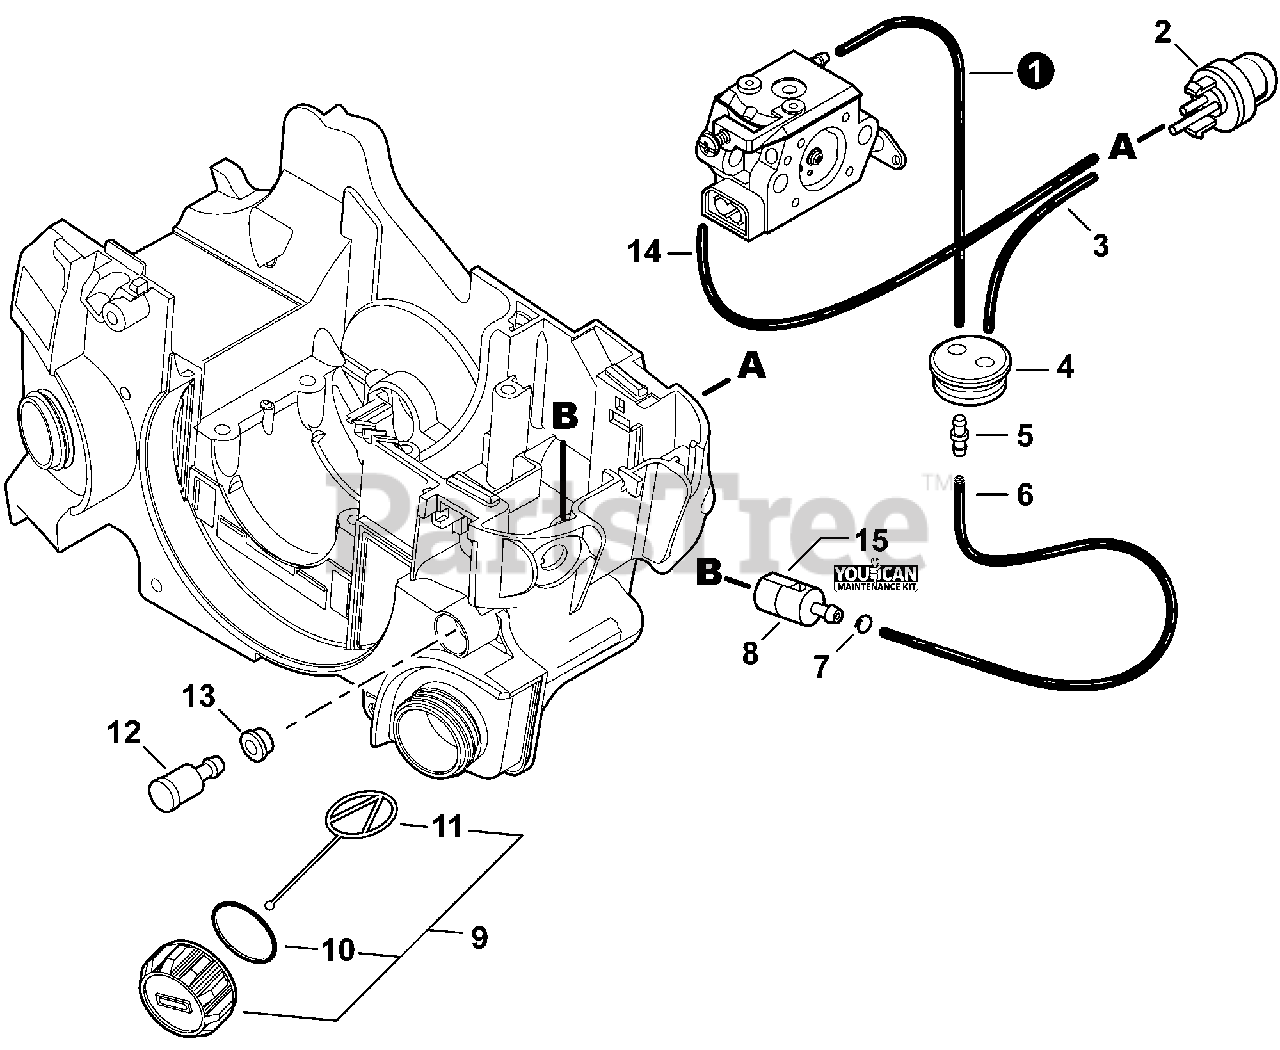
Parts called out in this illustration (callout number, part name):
1	PIPE, FUEL 3×5×85 BLACK
2	BULB, PURGE
3	PIPE, FUEL 2.4×5×80 BLACK
4	GROMMET, FUEL
5	CONNECTOR, PIPE
6	PIPE, FUEL 3×5×144 BLACK
7	CLIP Ø6
8	FILTER, FUEL
9	CAP ASSY, FUEL
10	O-RING 22
11	CONNECTOR, CAP L= 60 MM
12	VENT ASSY
13	GROMMET, FUEL
14	PIPE 2.4×5×125 BLACK
15	TUNE-UP KIT - YOUCANT
